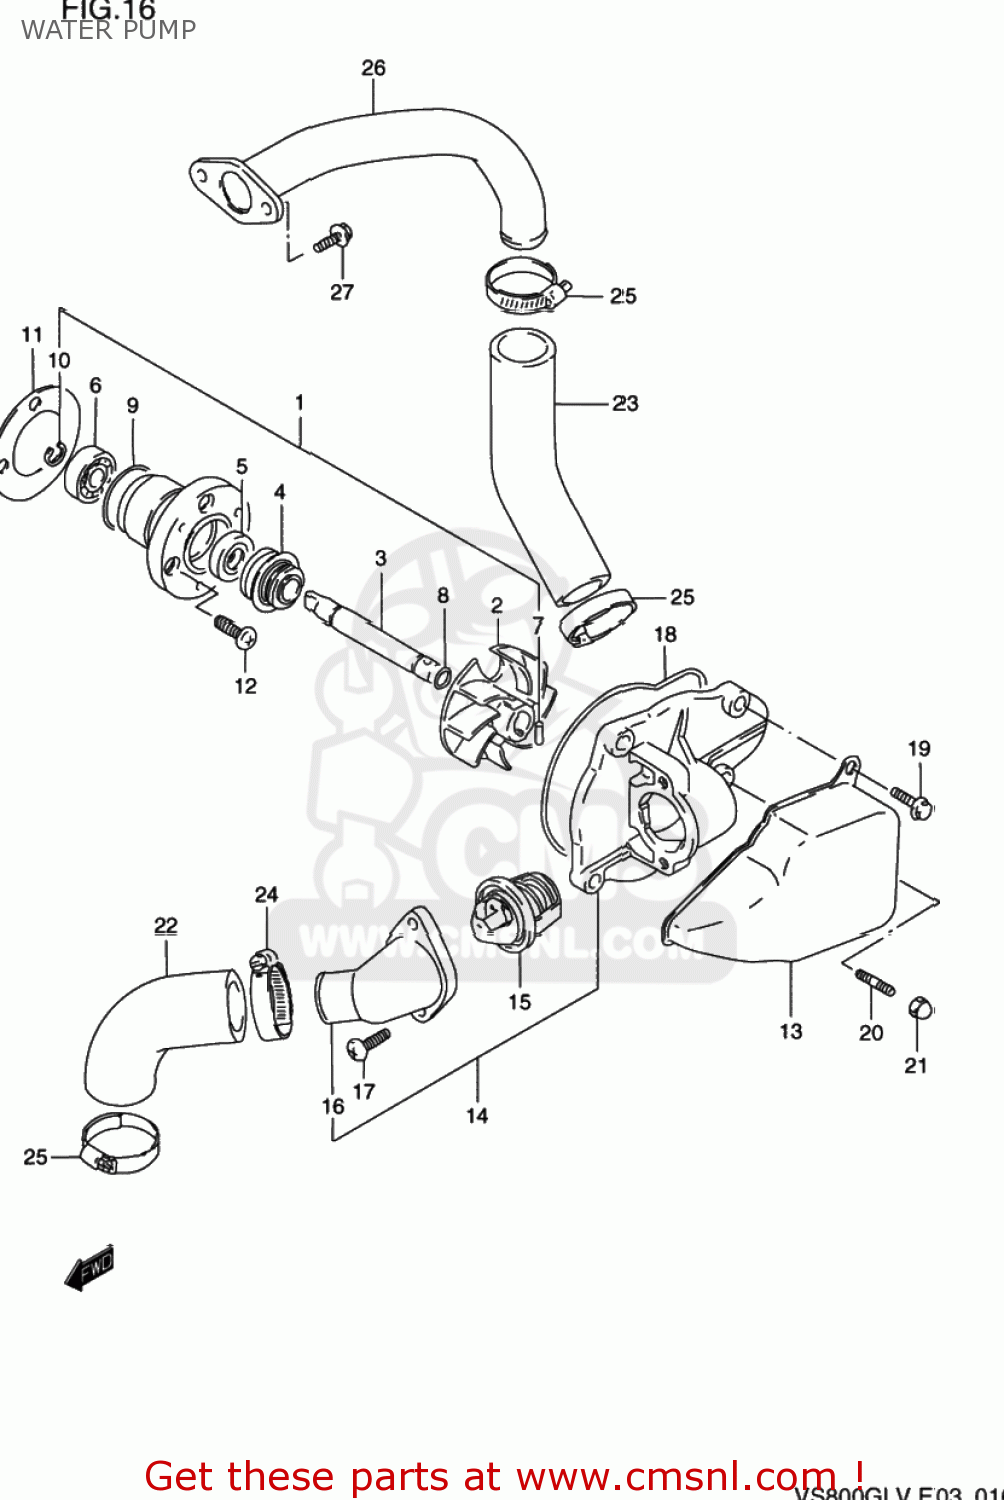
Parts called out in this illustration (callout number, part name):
1	PUMP ASSEMBLY,WATER
2	IMPELLER
3	SHAFT
4	SEAL,MECHANICAL
5	OILSEAL
6	BEARING,10X26X8
7	PIN
8	O RING
9	O RING
10	E RING
11	GASKET,WATER PUMP (NAS)
12	SCREW
13	COVER,WATER PUMP
14	CASE ASSY,WATER PUMP
15	THERMOSTAT,WATER
16	CONNECTOR
17	SCREW
18	O RING,WATER PUMP CAP
19	BOLT
20	STUD
21	NUT
22	HOSE,WATER PUMP IN
23	HOSE,WATER
24	CLAMP
25	CLAMP
26	PIPE,CYLINDER INLET
27	BOLT
